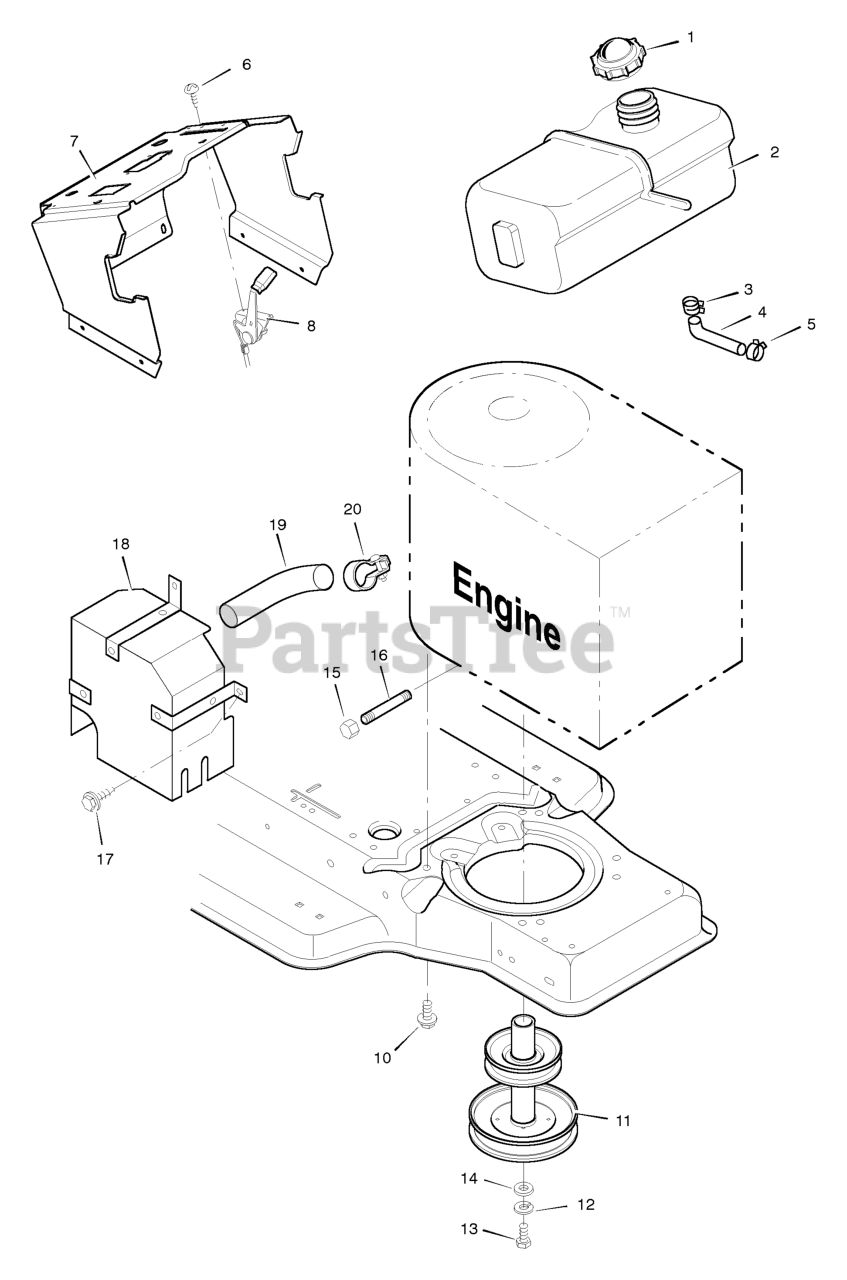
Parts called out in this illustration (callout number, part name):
1	Fuel Cap
2	Fuel Tank
3	Hose Clamp
4	Fuel Line
5	Hose Clamp
7	Support, Dash
8	Throttle Control
9	Engine *
10	Bolt, Engine Mount
11	Stack Pulley Assembly
12	Lockwasher
13	Bolt, Hex
15	Cap, Oil Drain
16	Pipe, Oil Drain
18	Shield, Heat
19	Pipe, Exhaust
